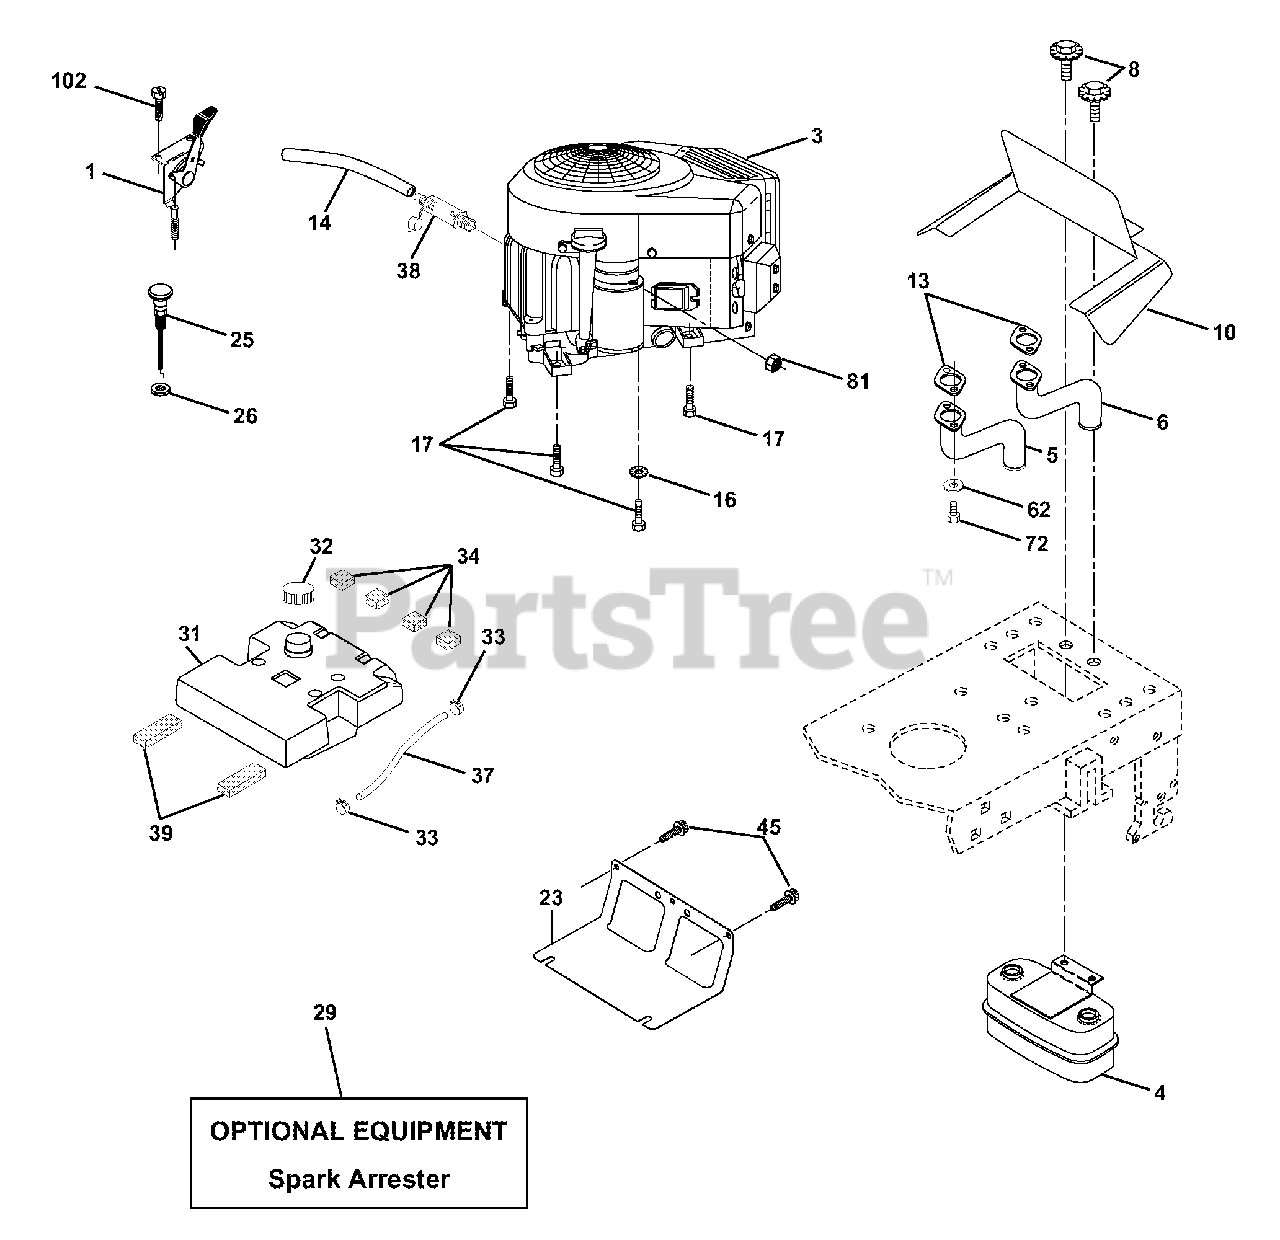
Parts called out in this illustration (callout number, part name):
1	Control Throttle
4	Muffler Asm Twin Lo-Tone
5	Pipe Exhaust LH Intek
6	Pipe Exhaust RH Intek
8	Bolt 5/16-18 UNC x 3/4 w/Sems
10	Shield Browning Intek II
13	Muffler Gasket
14	Tube Drain Oil Easy
16	Washer Lock Ext Tooth 3/8
17	Screw Thdrol 3/8-16 x 1-1/2
23	Shield Heat
25	Choke Control
26	Nut, Keps 3/8-24 UNF
29	Kit Spark Arrestor (Flat Scrn)
31	Tank Fuel 3 50 Rear
32	Cap Asm Fuel W/sym Vented
33	Clamp Hose Black
34	Pad, Spacer
37	Line Fuel
38	Plug Drain Oil Easy
39	Pad, Idler
45	Screw Hexwsh Thdr 3/8-16 x 3/4
62	Washer Lock 5/16
72	Screw Hex Hd Cap 5/16-18 x 3/4
81	Nut Keps Hex 1/4-20 UNC
102	Screw Hw Hd Hi-Lo #13-16 x 3/4
